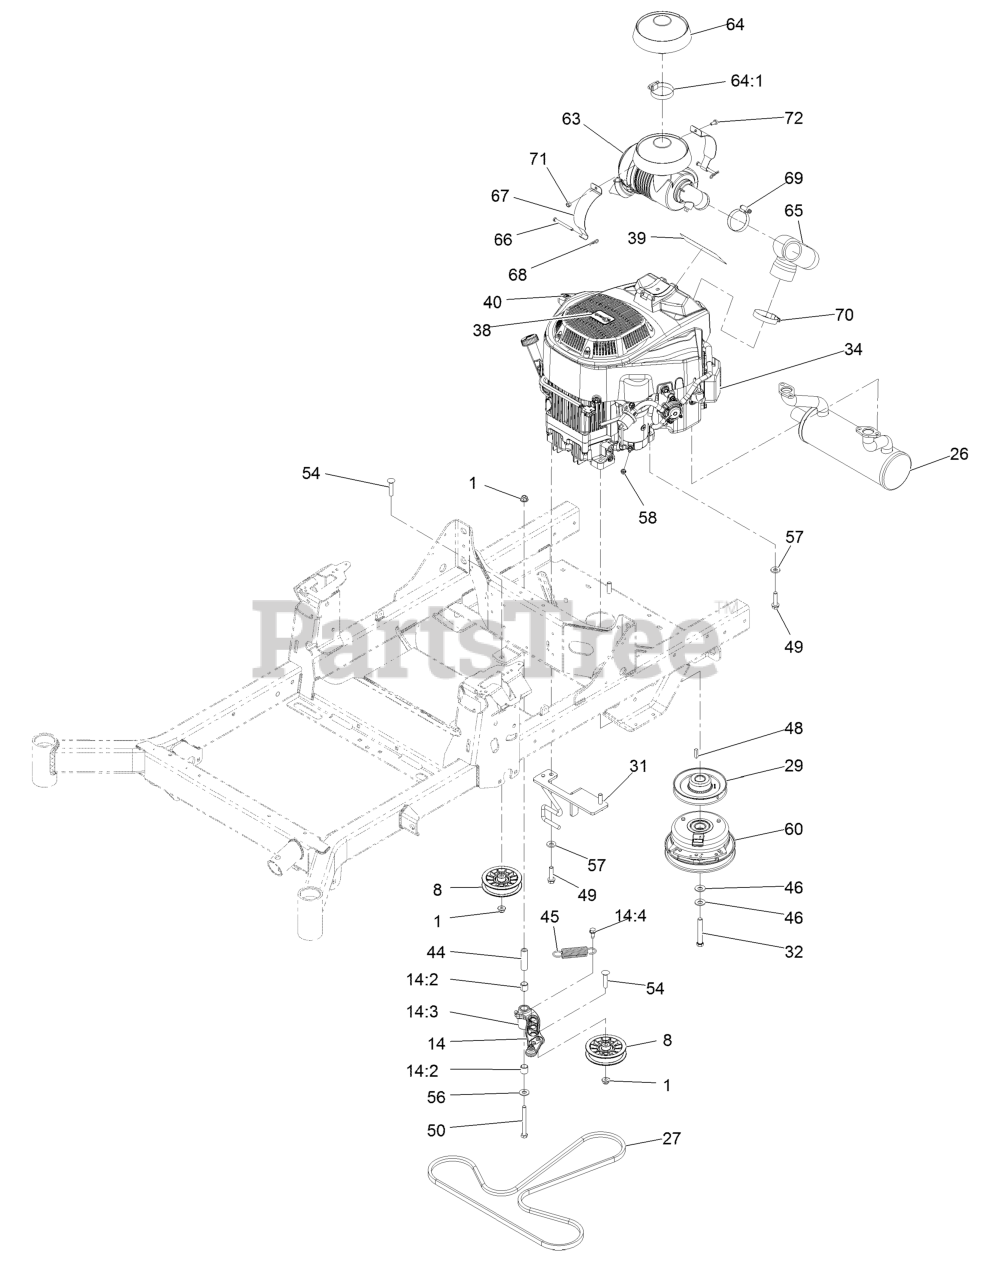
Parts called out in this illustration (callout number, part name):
1	Nut-Nyloc 3/8-16 Flg
8	Pulley-Flat
14	Idler Arm ASM
14:2	Sleeve-Bearing
14:3	Zerk-90deg 1/4-28
14:4	Screw-HWH 5/16-18 X 3/4 Tf
26	Muffler
27	Belt-V
29	Sheave-Engine
31	Anchor-Clutch
32	Screw-HH 7/16-20 X 3 W/Loctite
34	Engine-2P77F-HD
39	Decal - Air Canister Mount
40	Decal-Drain, Oil
44	Bushing-Pivot, Idler
45	Spring-Extension
46	Washer-Spring Disc 7/16
48	Key-Machine 1/4 X 1/4 X 1
49	Screw-HWH 3/8-16 X 1 1/2 Taptite
50	Screw-HH 3/8-16 X 3 1/2
54	Bolt-Carriage 3/8-16 X 1 3/4
56	Washer-3/8 Std
57	Washer-Spring Disc 3/8
58	Nut-Hex M6-1 Flg
60	Clutch - 1.00 HD
63	Air Cleaner ASM
64	Rain Cap Kit
64:1	Clamp-Hose
65	Hose-Intake
66	Pin-Clevis
67	Strap-Canister, Air
68	Hairpin-Cotter
69	Clamp-Hose
70	Clamp-Hose
71	Nut-Hex
72	Screw-HH
